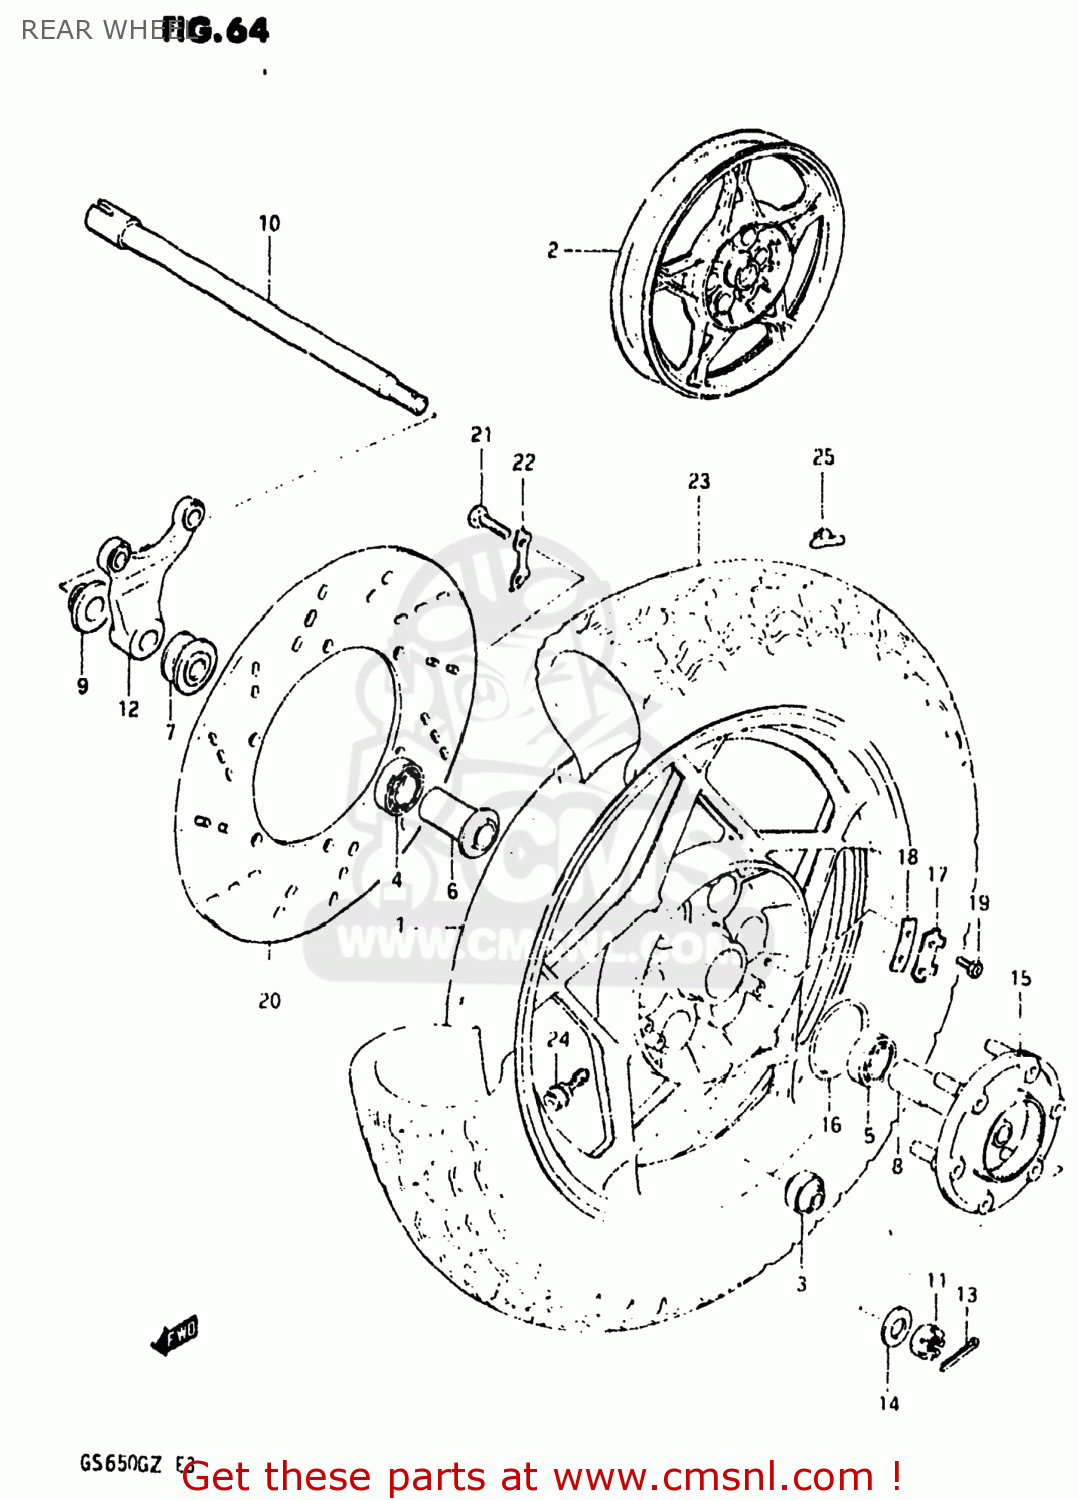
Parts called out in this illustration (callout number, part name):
1	WHEEL SET,REAR
2	CASTING WHEEL,REAR 2.50
3	BUSH
4	BEARING
5	BEARING
6	SPACER,REAR HUB BEARING
7	SPACER,REAR AXLE
8	SPACER,REAR AXLE,LEFT
9	SPACER,REAR AXLE,RIGHT
10	AXLE,REAR
11	NUT
12	BRACKET,RR,CALIPER
13	PIN,COTTER
14	WASHER(16.5X36X3.2)
15	JOINT ASSEMBLY,REAR HUB DRUM
16	O RING(D:2.1,ID:65)
17	WASHER (T:1.0)
18	WASHER,THRUST(T:1.6)
19	BOLT(6X16)
20	DISC,RR BRAKE
21	BOLT(8X25)
22	WASHER
23	TIRE
24	VALVE ASSEMBLY,WHEEL RIM,J
25	BALANCER,WHEEL
